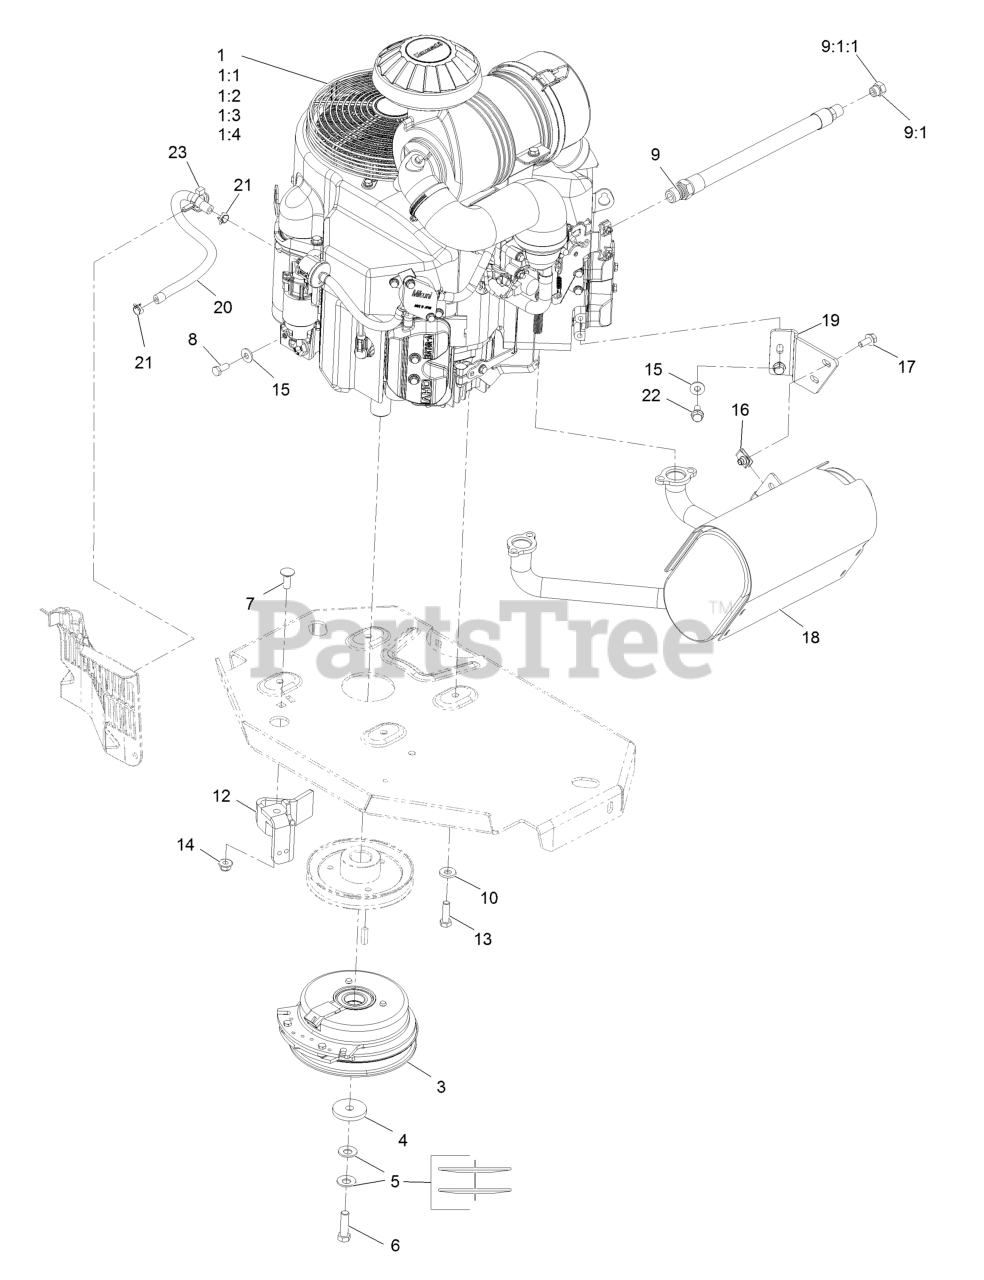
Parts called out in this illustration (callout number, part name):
1:1	Kawasaki 49065-2078 Engine Oil Filter
1:2	Kawasaki 49019-7001 Fuel Filter
1:3	Kawasaki 11013-7039 Safety Filter
1:4	Kawasaki 11013-7038 Air Filter
3	CLUTCH KIT
4	WASHER-CLUTCH
5	WASHER-SPRING
6	SCREW-HH 7/16-20 X 1 1/2 W/LOCTITE
7	SCREW-CARR
8	SCREW-HH
9	ENGINE OIL DRAIN HOSE ASM
9:1	PLUG-HH
9:1:1	O-RING
10	WASHER-BELLEVILLE
12	CLUTCH-ANCHOR
13	SCREW-HH
14	NUT-HF, NI
15	WASHER-SPRING
17	SCREW-HHF
18	MUFFLER
19	BRACKET-MUFFLER
20	HOSE-FUEL
21	CLAMP-HOSE
22	SCREW-HHF
23	CLAMP-HOSE
